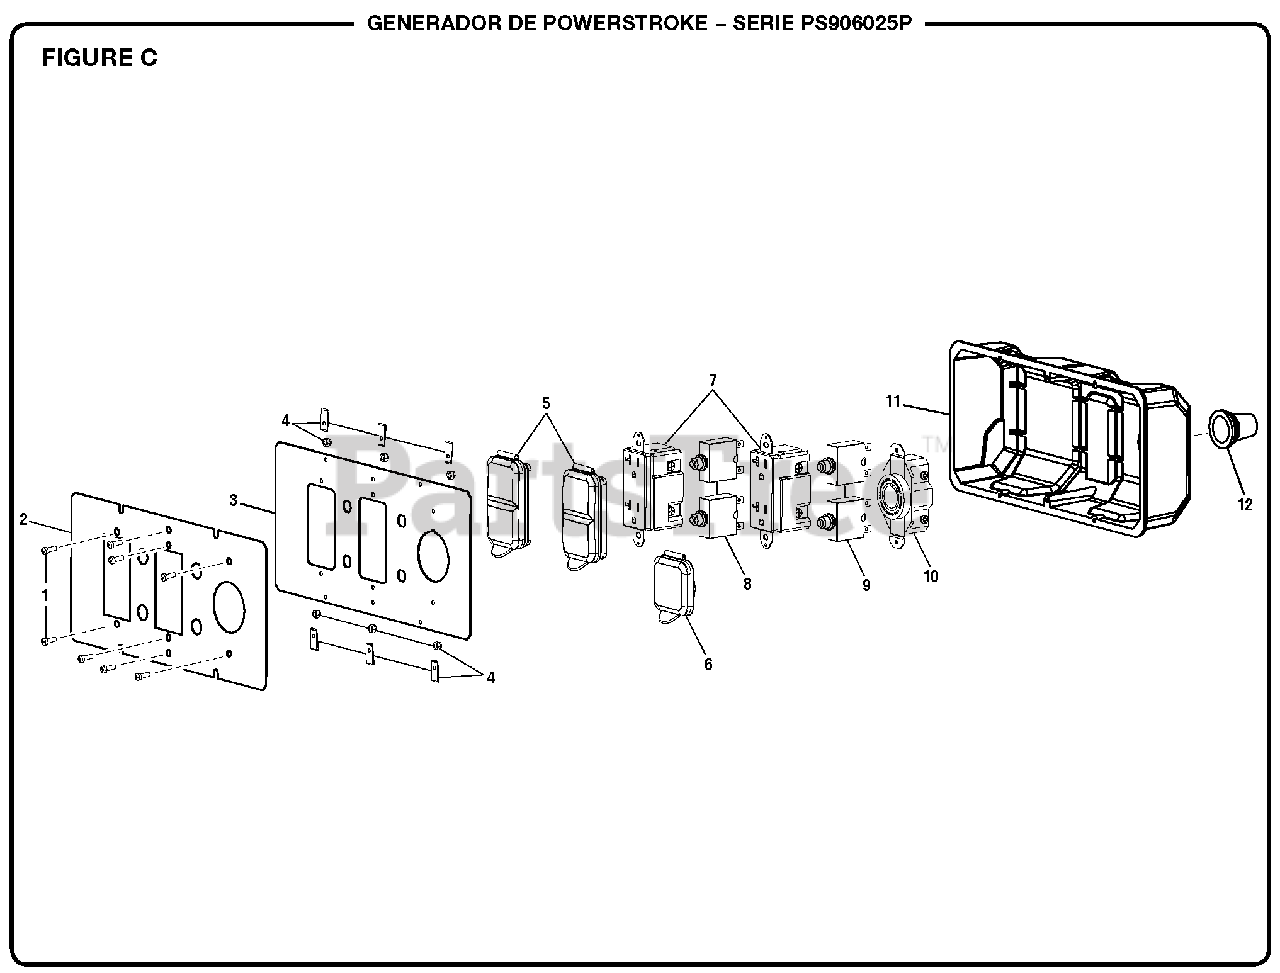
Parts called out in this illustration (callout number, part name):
1	Screw (6-20 x 3/8 in.)
2	Label (Power Outlet)
3	Front Panel
4	U-Clip Nut
5	Outlet Cover (120 Volt)
6	Outlet Cover (240 Volt)
7	Duplex Receptacle (120 Volt)
8	Circuit Breaker, 20 Amp
9	Circuit Breaker, 30 Amp
10	Twist Lock Receptacle (240 Volt)
11	Control Box (Back Panel)
12	Rubber Boot
